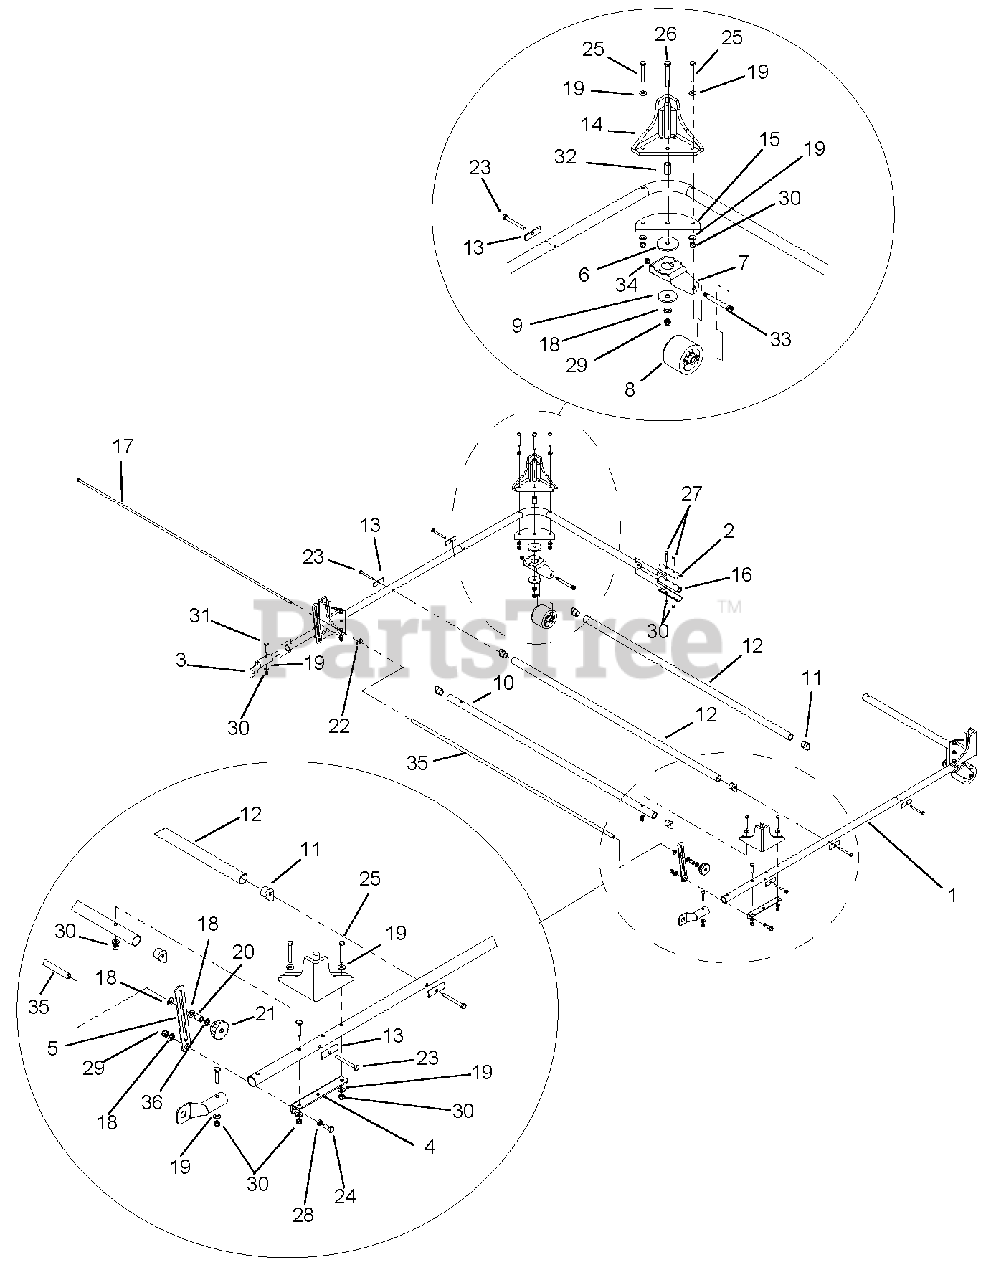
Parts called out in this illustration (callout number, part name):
1	Frame Side
2	Clamp, Half
3	End Cap, Tube
4	Angle Bracket
5	Bracket, Adjust
7	Caster Fork
9	Washer, Area Vac 35 29/64 x 1-3/4 x.134
10	Cross Brace, Forward
11	Tube Connector, Round To Round
12	Cross Brace Assembly, Middle
13	Clamp, Bracket
14	Support, Corner
15	Caster Plate
16	Insert, Tube
17	Bolt, Adjuster
18	Washer, Flat Steel .344 x .688 x .065 YWZC
19	Washer, Flat Steel .281 x .62 x .065 YWZC
20	Spacer, .500 OD x .625 L
21	Knob, Fluted
22	Washer, Flat Steel .438 x 1.00 x .083 YWZC
23	Bolt, Hex .25-20 x 2.50 Grade 5 YWZC
24	Bolt, Hex .31-18 x .75 Grade 5 YWZC
25	Bolt, Hex .25-20 x 2.00 Grade 5 YWZC
26	Bolt, Hex .31-18 x 2.50 Grade 5 YWZC
27	Bolt, Hex .25-20 1.50 Grade 5 YWZC
29	Nut, Nylock .312-18 YWZC
30	Nut, Nylock .250-20 YWZC
31	Bolt, Contour Head 1/4-20 x 1.50
33	Bolt, Shoulder Socket 3/8 x 2-3/4
34	Nut, Lock Center, .25-20 YWZC
35	Tube, Plated 1/2 x .065
36	Washer, Lock .38 Internal Star YWZC
